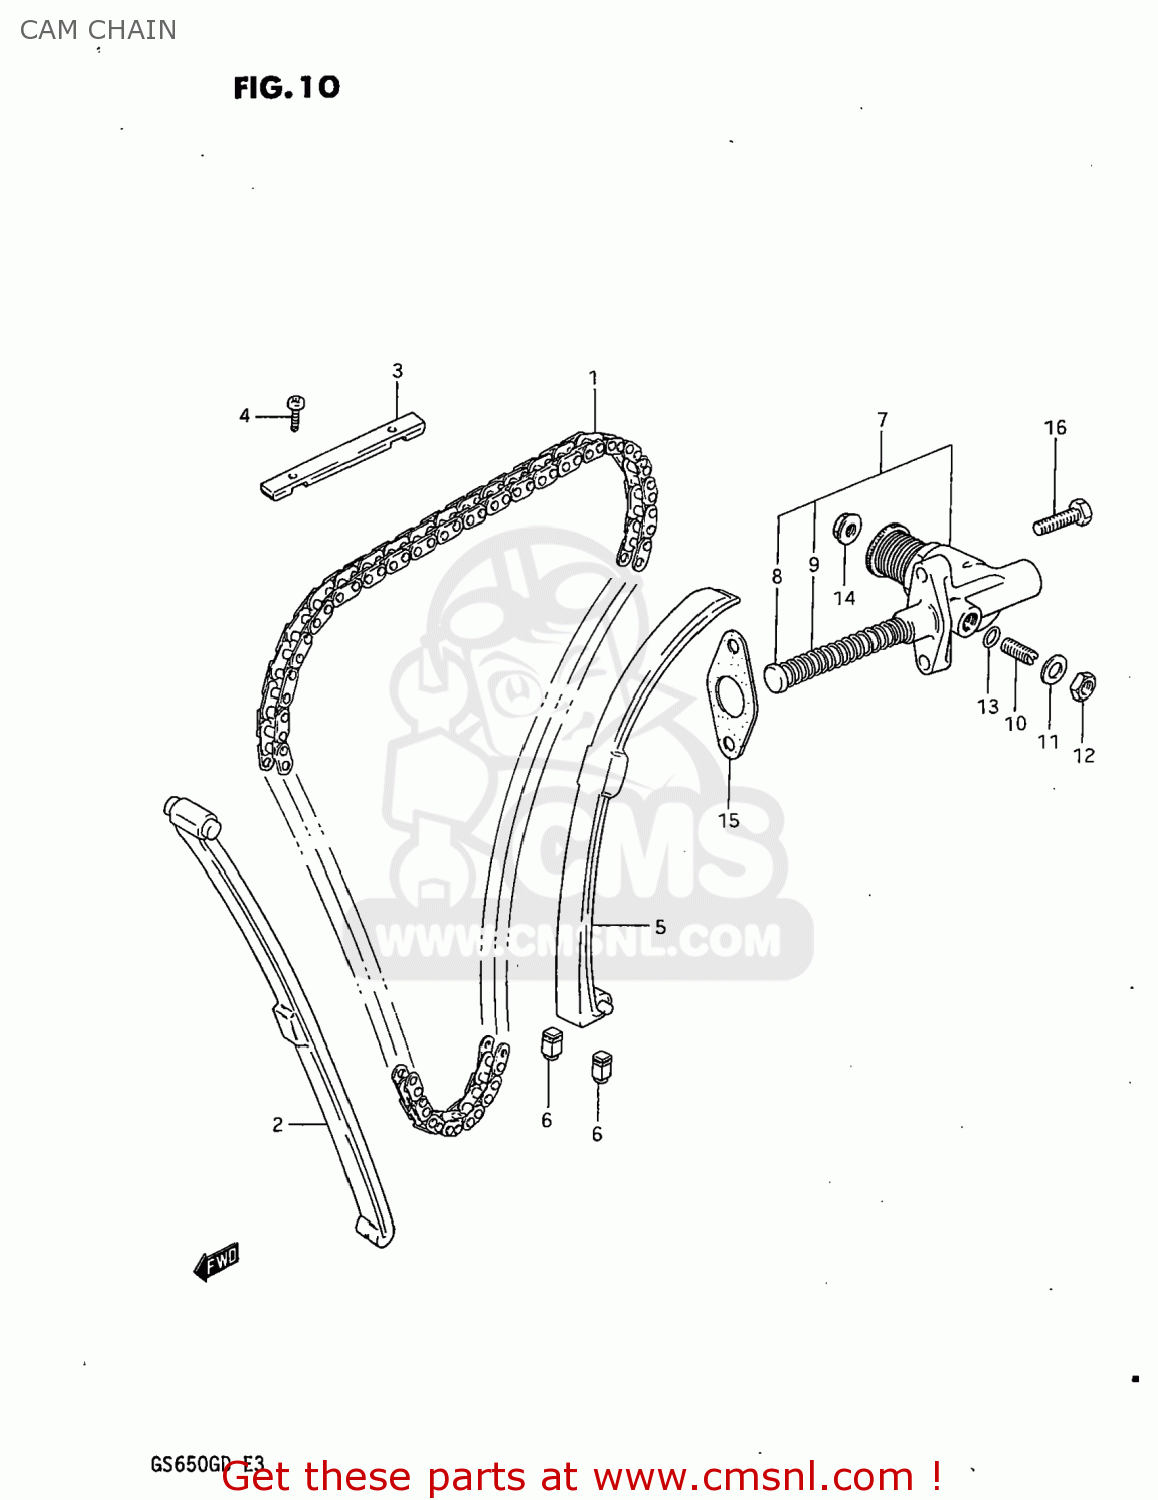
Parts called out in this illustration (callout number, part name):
1	CHAIN,CAMSHAFT DRIVE(120L)
2	GUIDE,CAM CHAIN
3	GUIDE,CAM CHAIN
4	SCREW
5	TENSIONER,CAM CHAIN
6	CUSHION,CAM CHAIN TENSIONER
7	ADJUSTER ASSEMBLY,TENSIONER
8	ROD,PUSH
9	SPRING
10	SCREW
11	WASHER
12	NUT
13	O-RING
14	NUT
15	GASKET,TENSIONER ADJUSTER (MCA)
16	SCREW (6X25)
